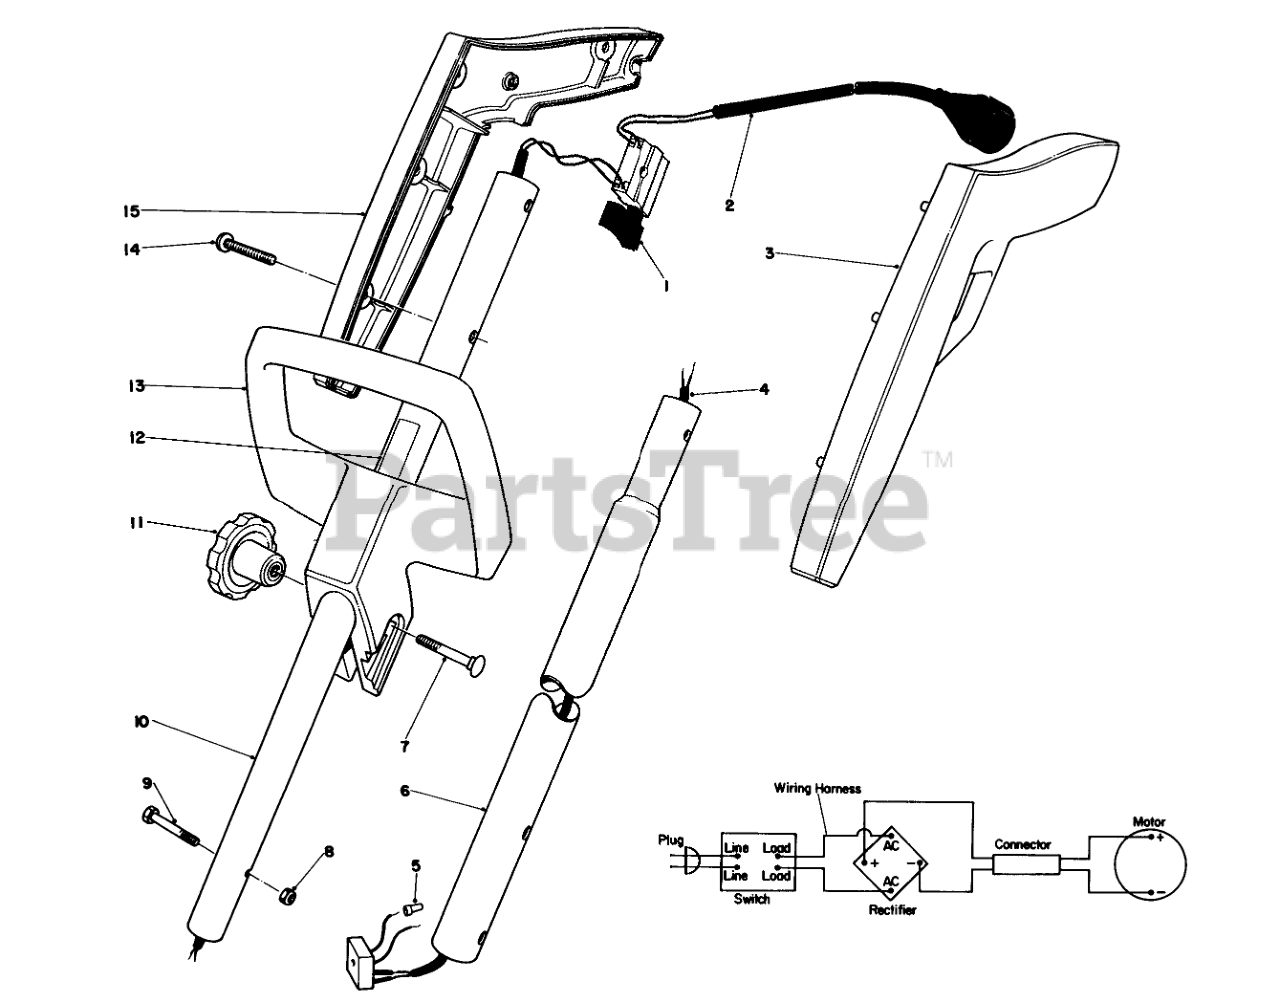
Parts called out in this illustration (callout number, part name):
1	SWITCH SINGLE SPEED
2	Cord-Power
3	Grip L.H.
4	Wiring Harness w/Rectifier
5	Wire Connector
6	Tube-Lower
7	BOLT-CARR
8	NUT-LOCK, NI
9	HEX HD MACHINE SCREW
10	Tube-Upper
12	Decal-Caution
13	ADJUSTABLE HANDLE
14	Screw
15	R.H. GRIP
